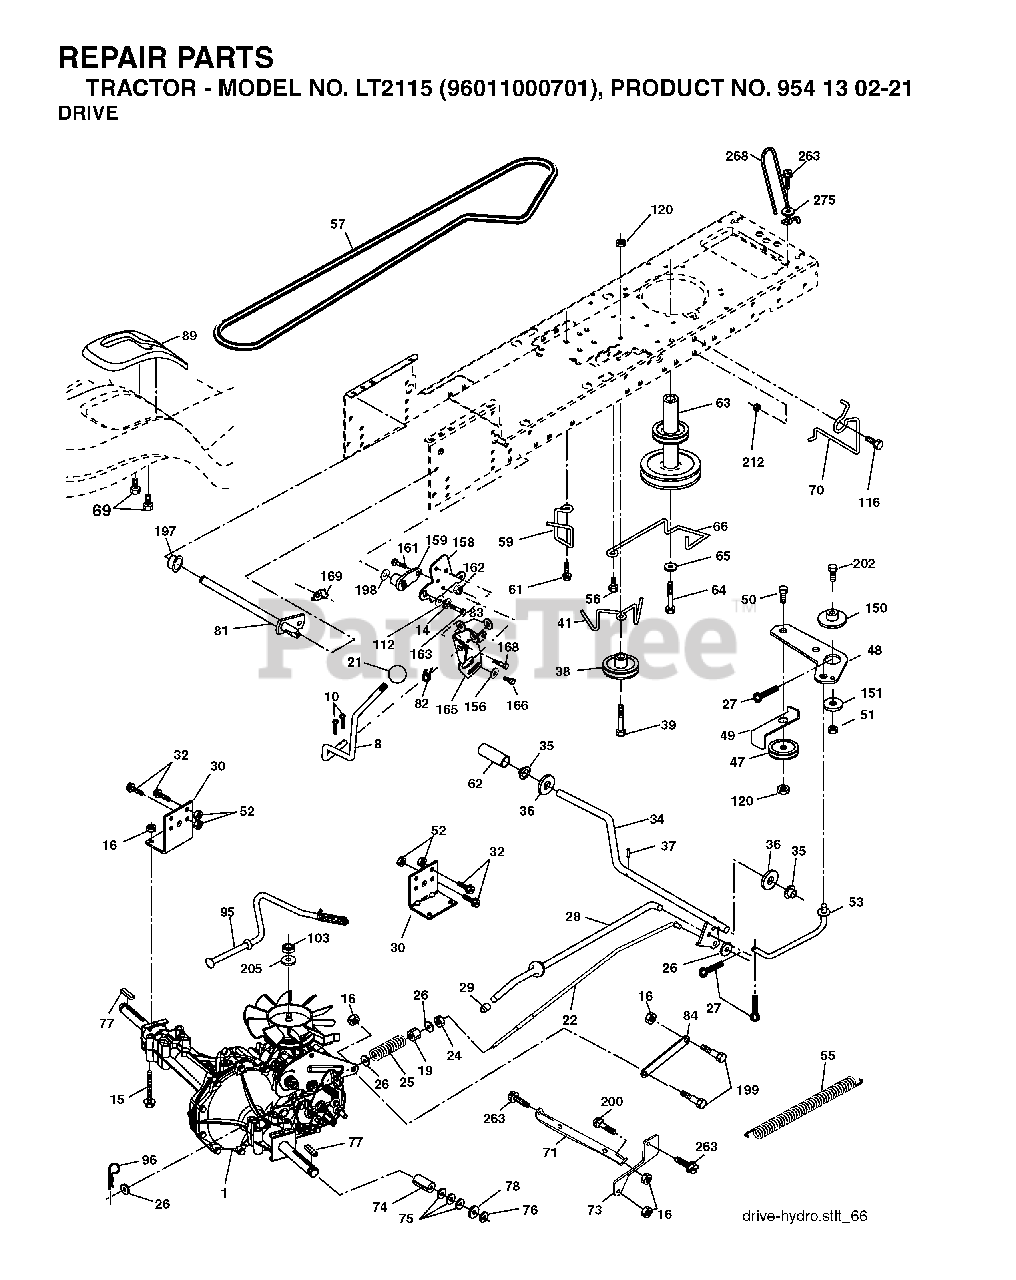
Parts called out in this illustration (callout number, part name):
8	ROD.SHIFT.FENDER.ADJ.STLT
10	PIN COTTER
14	LOCKWASHER
15	BOLT HEX 5/16-18 GR 5
16	NUT.71038.31-18.HEX.NYLOCK
19	NUT
21	KNOB.DUCKHEAD.1/2
22	ROD BRAKE HYDRO
24	NUT
25	SPRING ROD LT
27	COTTER PIN
28	ROD, PARKING BRAKE
29	PLUNGER CAP
30	BRKT, MOUNT TRNSAXLE
32	BOLT
34	SHAFT, FOOT PEDAL
35	BEARING.NYLON
36	WASHER LT
37	DRIVE PIN
38	PULLEY IDLER COMPOSITE
41	KEEPER, BELT IDLER
47	IDLER PULLEY
48	BELLCRANK, CLUTCH
49	RETAIN BELT
50	BOLT.3/8-16X1.50
51	LOCKNUT
52	LOCKNUT
53	LINK, CLUTCH LT
55	SPRING, RETURN LT
56	SCREW.3/8-16
57	DRIVE BELT, LTH & YTH TRACTORS
59	KEEPER, BELT CENTER
61	SCREW 3/8-16X.875
62	PEDAL COVER T
64	BOLT HEX 7/16-20X4-1/4"
65	LOCKWASHER
66	KEEPER BELT ENGINE
69	SCREW.HI-LO.CONSOLE
71	STRAP TORQUE LH HYDRO
73	STRAP TORQUE RH HYDRO
74	SPACER AXLE
76	E-RING LT
77	SQUARE KEY
81	SHAFT ASM CROSS TAPERED
82	SHIFT SPRING
83	WASHER
89	CONSOLE SHIFT STLT
95	CONTROL ASM. BYPASS HYDRO
96	RETAINER M
103	NUT.HEX.1/2-20
112	WASHER LT
116	BOLT D
120	NUT LOCK FLG 3/8-16 UNC
150	SPACER, RETAINER
151	WASHER 12/32X2X10GA
156	WASHER.SRRTD.5/16
158	BRACKET
159	HUB.SHIFT
161	BOLT
162	NUT.CROWNLOCK.1/4
165	RP BRACKET
168	BOLT.SHOULDER.5/16-18X
169	PLATE.FASTENING.CROSS.SHAFT
197	NYLINER SNAP 5/8" ID
198	WASHER.NYL.7/8IDX.105"HYD CR
199	BOLT SHOULDER 5/16-18 UNC
200	BOLT
202	BOLT
205	WASHER
212	NUT
263	SCREW, 3/8-16X3/4
275	WASHER
